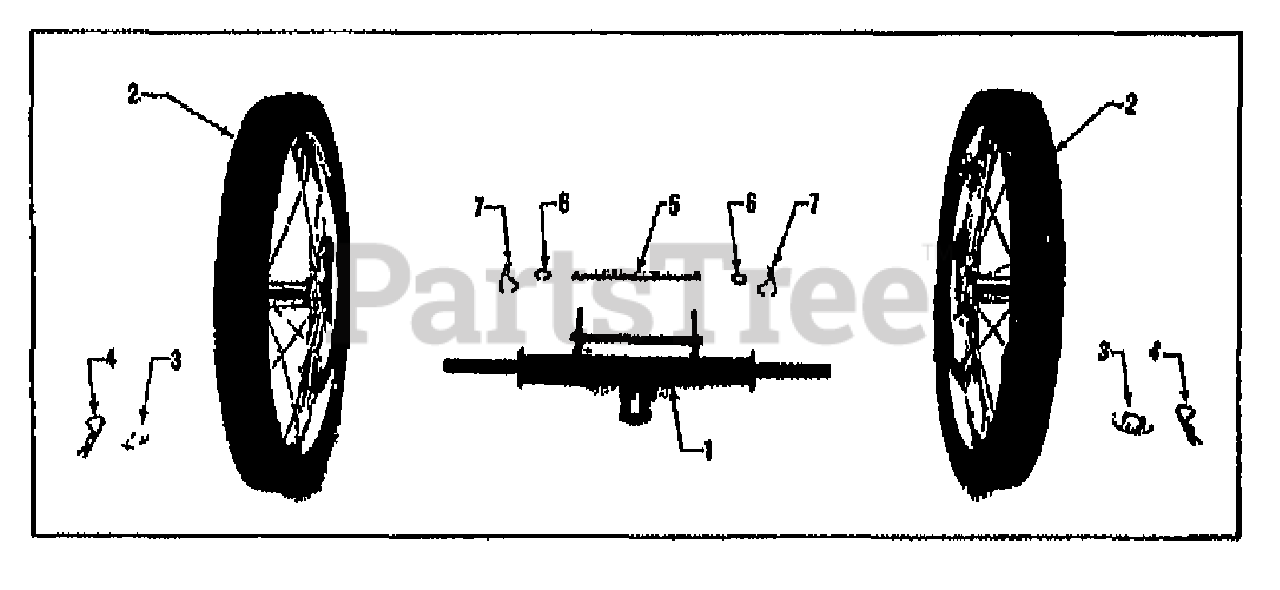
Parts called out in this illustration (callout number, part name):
1	AXLE-WELDMENT PNT (WELDED UNIT)
2	ASSM-WHEEL M16 CART
3	WASHER-1.75X.625X.11
4	PIN-HITCH ZP (USED TO ATTACH WHEEL TO AXLE)
5	PIN # .375 X 6.125
6	WASHER-FLAT 3/8 SAE
7	PIN-HITCH ZP (USED TO ATTACH WHEEL AXLE ASSEMBLY TO CHASSIS)
